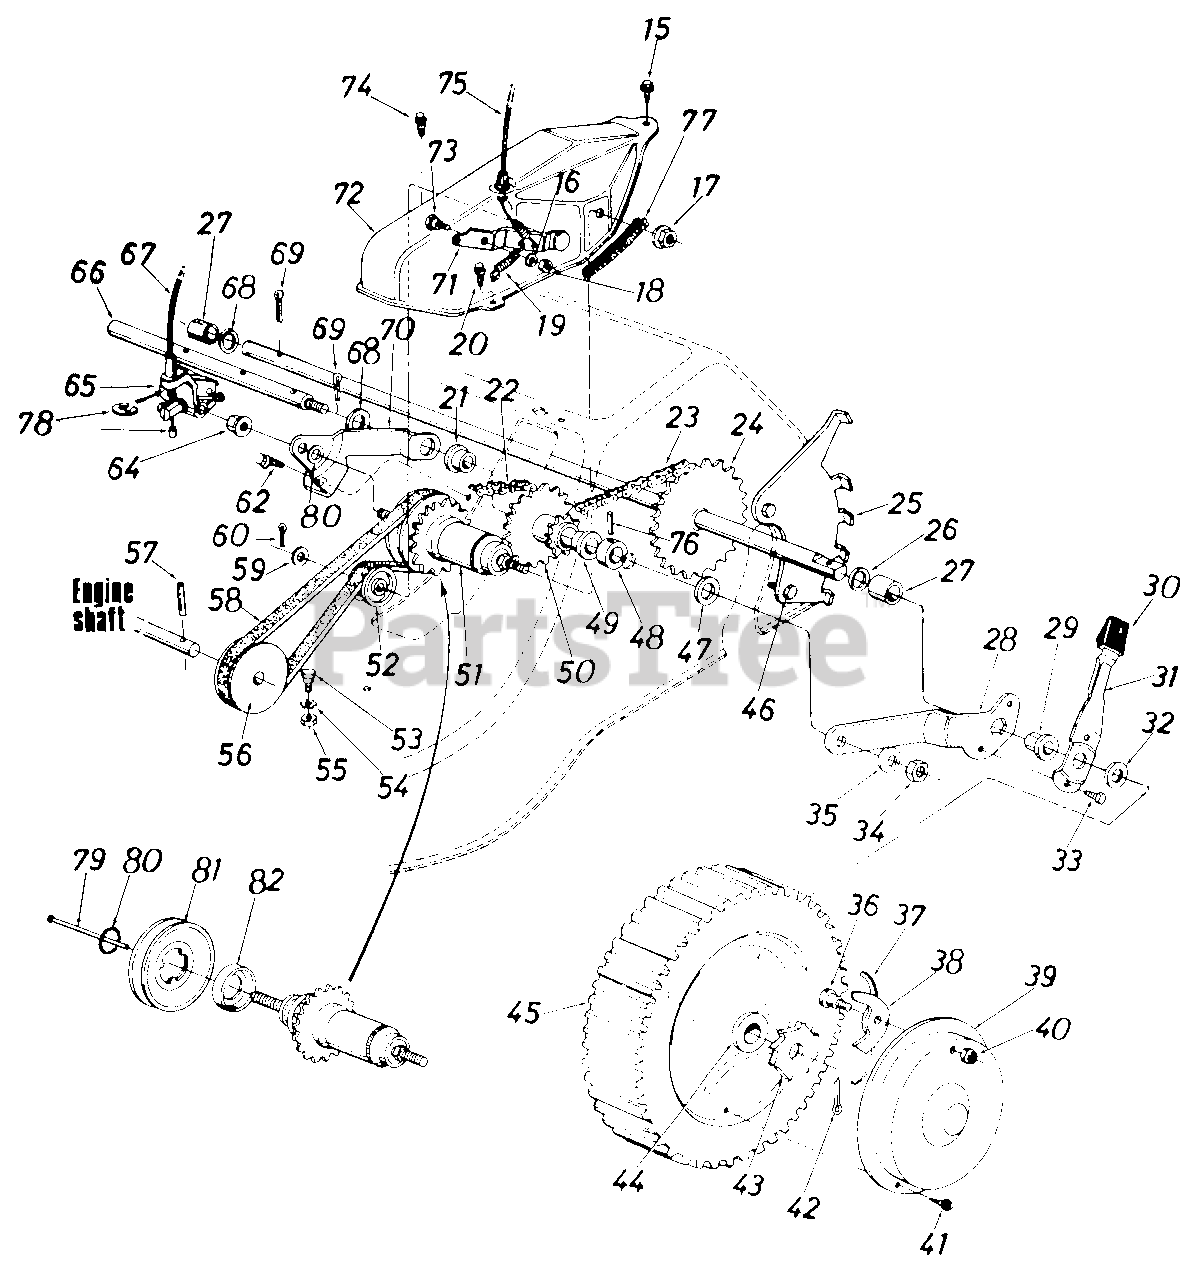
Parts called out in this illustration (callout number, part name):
15	SCREW-HEX DRILLING #10 X .50
16	LOCK WASHER 1/4 DIA
17	NUT-HEX BC 3/8-24
18	NUT-HEX 1/4-20
19	SPRING-EXTENSION
20	SCREW-HEX WASH SF TAPP
21	BEARING-FLANGE
22	#48 CHAIN-1/2 PITCH-38 LINKS
23	#48 CHAIN 1/2 PITCH X 31 LINKS
24	SHAFT ASSY-REAR
25	PLATE-INDEX-RR-LH
26	WASHER-FL
28	BRACKET-PIVOT-LH
29	BEARING-HEX FLANGE .506 ID
30	KNOB
31	LEVER-SPRING
32	WASHER-FL-.531 X .930 OD X .050
33	SCREW-HEX B-TAP 1/4 X .38
34	NUT-HEX JAM 3/8-18
35	WASHER-BELL .400 ID X .88 X .060
36	SCREW-SHLD .342 DIA X .268
37	SPRING-NYLON
38	PAWL
39	HUB CAP
40	NUT-INS LOCK 1/4-20
41	SCREW-PAN HD TAPP
42	PIN-COTTER-1/8 DIA X 1.00
43	RACHET-WHEEL
44	BEARING-BALL
45	WHEEL ASSY W/TIRE
46	SCREW-HEX L-WASH HD
47	WASHER-BELL .3/8ID X 1.12OD X .030
49	BEARING-FLANGE
50	SPROCKET ASSY-9T & 21T
51	HUB-W/18T SPROCKET
52	PULLEY-IDLER-FLAT
53	SCREW-SHLD .437 DIA X .180
54	WASHER-LOCK-5/16
55	NUT-HEX 5/16-18
56	PULLEY-ENGINE-1/2 V
57	PIN-SPIROL 3/16X1.50
58	BELT-V 1/2 X 26.0
59	WASHER-FL-.531 X .930 OD X .050
60	PIN-COTTER-1/8 DIA X 1.00
62	SCREW-HEX HD TAP
64	NUT-HEX BC 3/8-24
65	BELL CRANK-3-SP SHIFT
66	SHAFT-PULLEY
67	CABLE-SHIFT
68	WASHER-FL-.531 X .930 OD X .050
69	PIN-COTTER-3/32 DIA X 1.00
70	BRACKET-3 SPEED
71	BRACKET ASSY-IDLER
72	SCREW-SHLD
73	SCREW-SHLD
74	SCREW-HEX HD TAP 1/4-20 X 7.5
75	CABLE-CLUTCH
76	PIN-SPRING SPIR 3/16 X 1.00
77	STRIP-TRIM-12IN
78	RING-SNAP
79	PIN-SHIFTING
80	RING-SNAP
81	PULLEY-1/2 V
82	COVER-DUST
